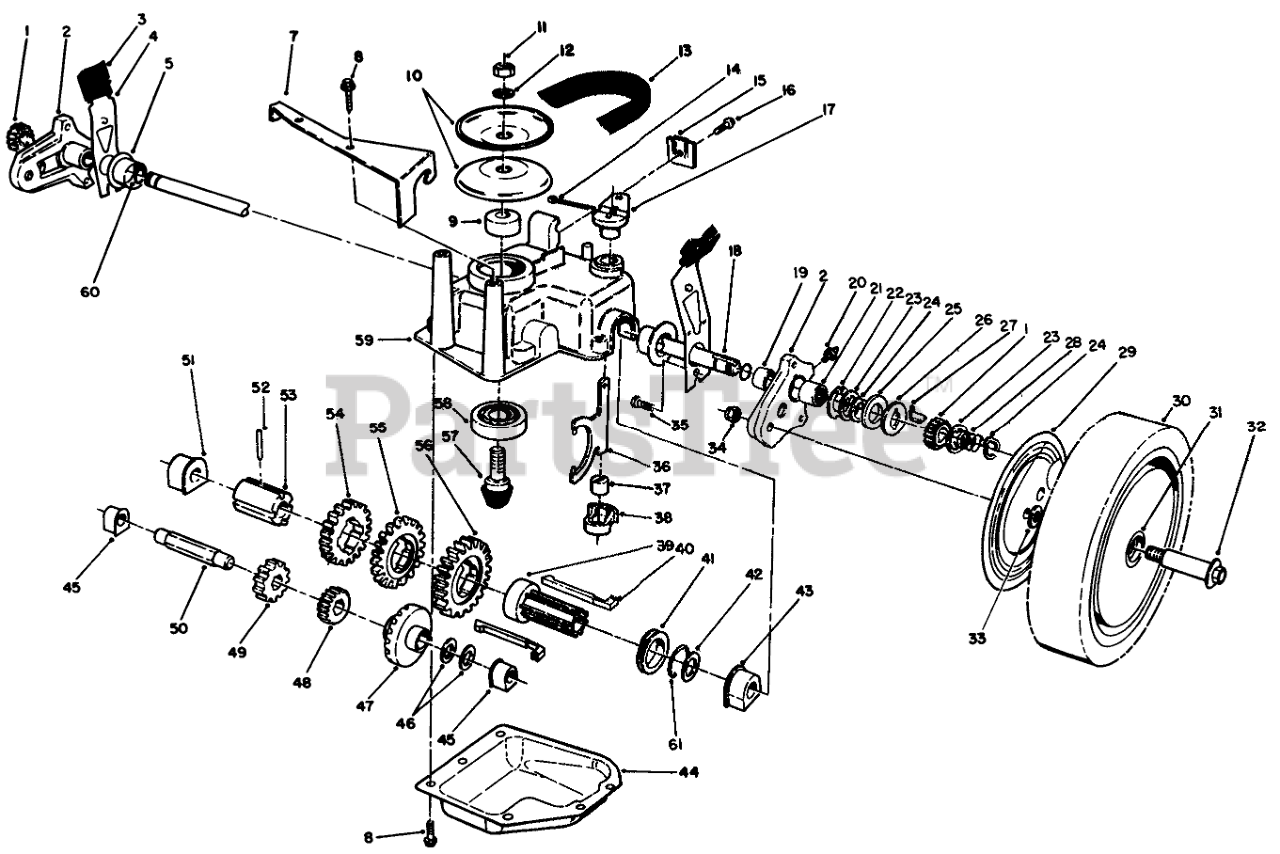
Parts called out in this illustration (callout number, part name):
1	GEAR-PINION
2	Pivot Arm Assembly (Incl. Ref #19, 20, & 21)
3	KNOB-ARM
4	SPRING ARM ASM SP
5	CAP-END
7	Bracket-Guide
8	SCREW-HWHTF
9	SPACER
10	Pulley Half
11	NUT-HEX
12	WASHER-FLAT
13	V-BELT E
14	PIN-COTTER
15	Cable Clamp
16	SCREW-HWHTF
17	SHIFT LEVER
18	SHAFT-OUTPUT
19	BUSHING
20	FITTING-GREASE
21	BEARING-ROLLER
22	WASHER-ARM, PIVOT
23	WASHER-THRUST, KEYED
24	RING-CLIP, LOCKING
25	RING-FRICTION
26	WASHER-CLUTCH
27	KEY-ROCKING, LH
28	SPRING-COMPRESSION
29	WHEEL COVER
30	Wheel-Tire & Gear Ass-y (Incl. Ref. #31)
31	BUSHING
32	WHEEL BOLT
33	WASHER
34	Nut
35	SCREW-HWH
36	YOKE-SHIFT
37	BUSHING-YOKE
38	RETAINER-FORK, SHIFT
39	SHIFT KEY SLEEVE
40	SHIFT KEY
41	SHIFT COLLAR
42	WASHER-PLAIN
43	BUSHING-OUTPUT
44	Cover-Gearcase
45	BUSHING
46	WASHER-THRUST
47	Gear-Bevel
48	PINION-20T
49	PINION-25T
50	SHAFT-INTERMEDIATE
51	BUSHING
52	PIN-SPRING
53	SLEEVE-GEAR
54	GEAR-39T
55	GEAR-44T
56	GEAR-49T
57	Gear-Pinion
58	BEARING-BALL
59	CASE-GEAR, UPPER
60	O-RING
61	CLIP-SPRING
